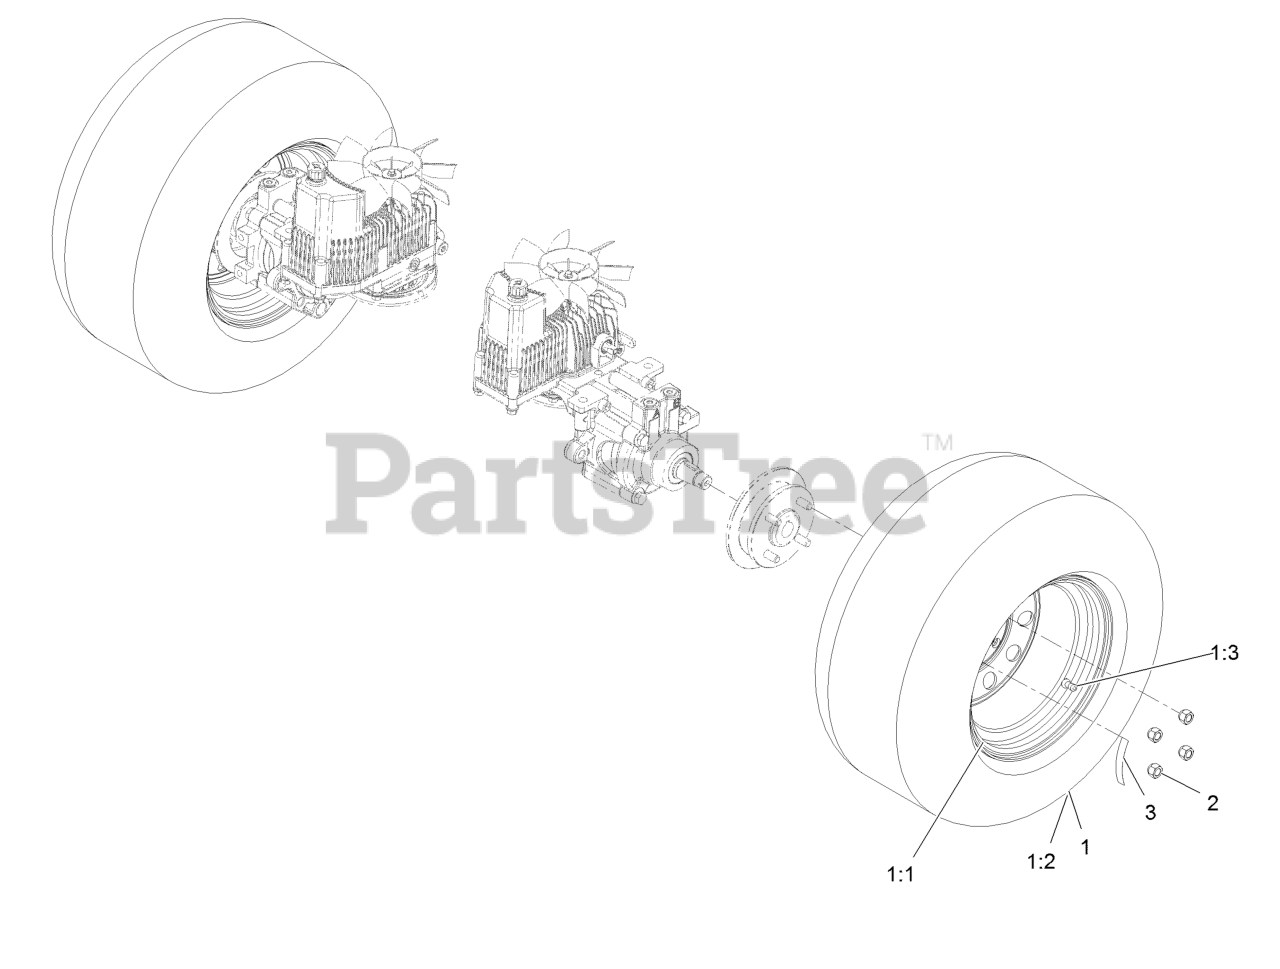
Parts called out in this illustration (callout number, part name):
1	Wheel And Tire ASM
1:3	Stem-Valve
2	Nut-Lug 1/2-20
3	Decal - Torque, Wheel Hub Lug
